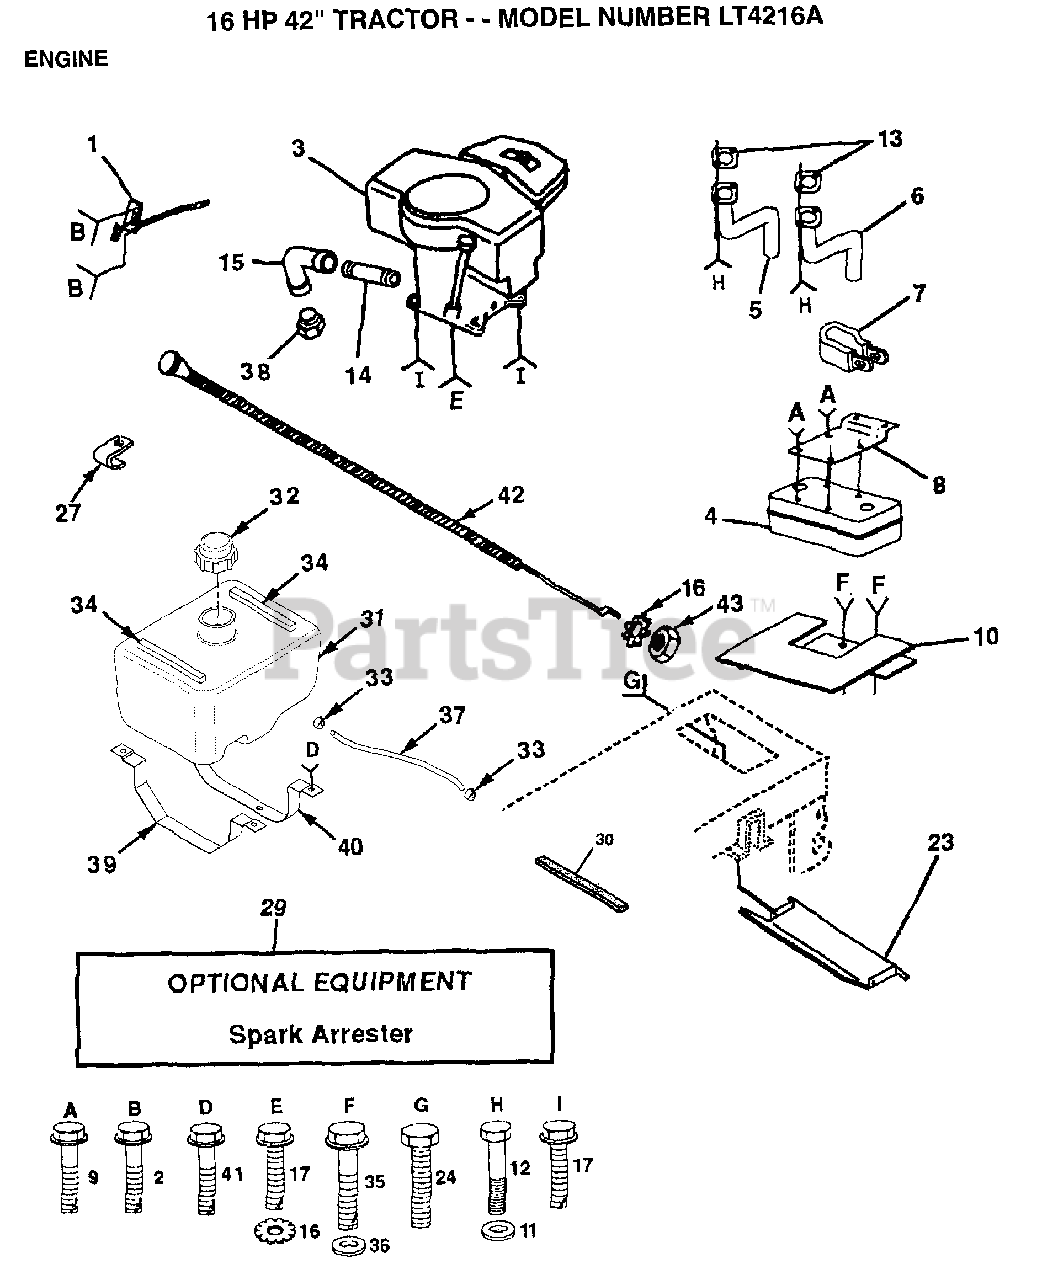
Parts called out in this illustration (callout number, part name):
1	CONTROL.THROTTL
2	SCREW LT
3	ENGINE, B&S
5	EXHAUST ASM LH
7	CLAMP.TUBE.DBL.EN
8	BRACKET MUFFLER
9	SCREW ST
10	SHIELD HEAT LT
14	PIPE NIPPLE LT
15	ELBOW
16	LOCKWASHER
17	SCREW LT
23	HEAT SHIELD
24	SCREW
27	"CLIP,INSULATOR"
31	TANK FUEL 1.9 NAT
32	CAP ASM FUEL
33	HOSE CLAMP
34	"STRIP,FORM"
35	SCREW
36	WASHER
37	FUEL LINE T
39	STRAP TANK FUEL
40	STRAP TANK FRONT
41	SCREW
42	CONTROL.CHK.26.38
